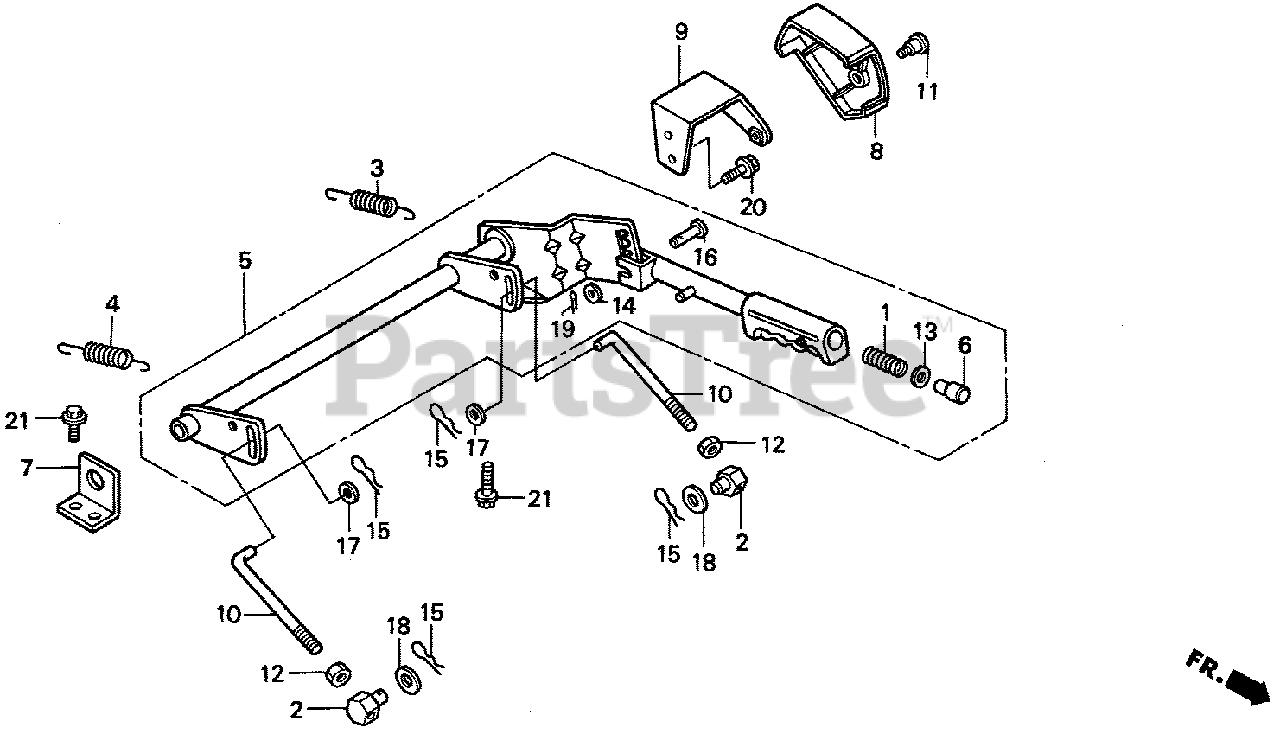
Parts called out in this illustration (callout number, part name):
1	SPRING, PUSH ROD
2	PIN, RR. LINK ADJUSTING
3	SPRING, DECK LIFT
5	LEVER ASSY., HEIGHT ADJUSTING *NH105* (MAT BLACK)
6	KNOB, PUSH ROD *NH105* (MAT BLACK)
7	PLATE, HEIGHT ADJUSTING LEVER
8	COVER, HEIGHT ADJUSTING LEVER *NH105* (MAT BLACK)
9	BRACKET, HEIGHT ADJUSTING LEVER
10	BAR, ADJUSTING
11	BOLT A, COWL SETTING (NOT AVAILABLE)
12	NUT, SELF-LOCK (OHASHI)
13	WASHER (11MM)
14	WASHER, PLAIN (9MM)
15	PIN, LOCK (2.3MM)
16	PIN, HEIGHT ADJUSTING LEVER
17	WASHER, PLAIN (12MM)
18	WASHER, PLAIN (14MM)
19	PIN, SPLIT (2.0X15)
20	BOLT, FLANGE (6X16)
21	BOLT, FLANGE (8X16)
